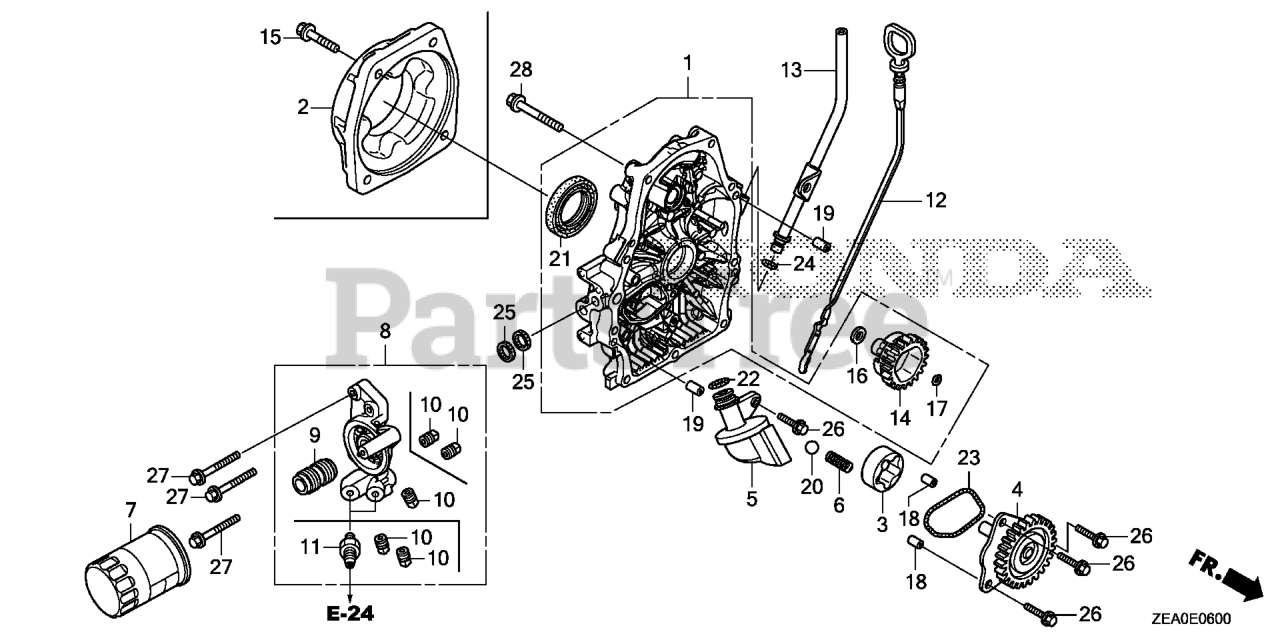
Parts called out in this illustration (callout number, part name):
1	COVER ASSY., CRANKCASE
3	ROTOR, OIL PUMP (OUTER)
4	GEAR, OIL PUMP
5	STRAINER, OIL
6	SPRING, RELIEF VALVE
7	FILTER, OIL
8	BASE, OIL FILTER
9	HOLDER, OIL FILTER
10	BOLT, SEALING
12	GAUGE, OIL LEVEL
13	PIPE, OIL LEVEL
14	HOLDER, GOVERNOR WEIGHT
16	WASHER (6X16)
17	CLIP, GOVERNOR HOLDER
18	PIN, DOWEL (8X10)
19	PIN, DOWEL (8X14)
20	BALL, STEEL (#15) (15/32)
21	OIL SEAL (38X58X9)
22	O-RING (14.8X2.4)
23	O-RING, OIL PUMP
24	O-RING (8.8X1.9)
25	GASKET, OIL PASSAGE
26	BOLT, FLANGE (6X20)
27	BOLT, FLANGE (6X35)
28	BOLT, FLANGE (8X45)
